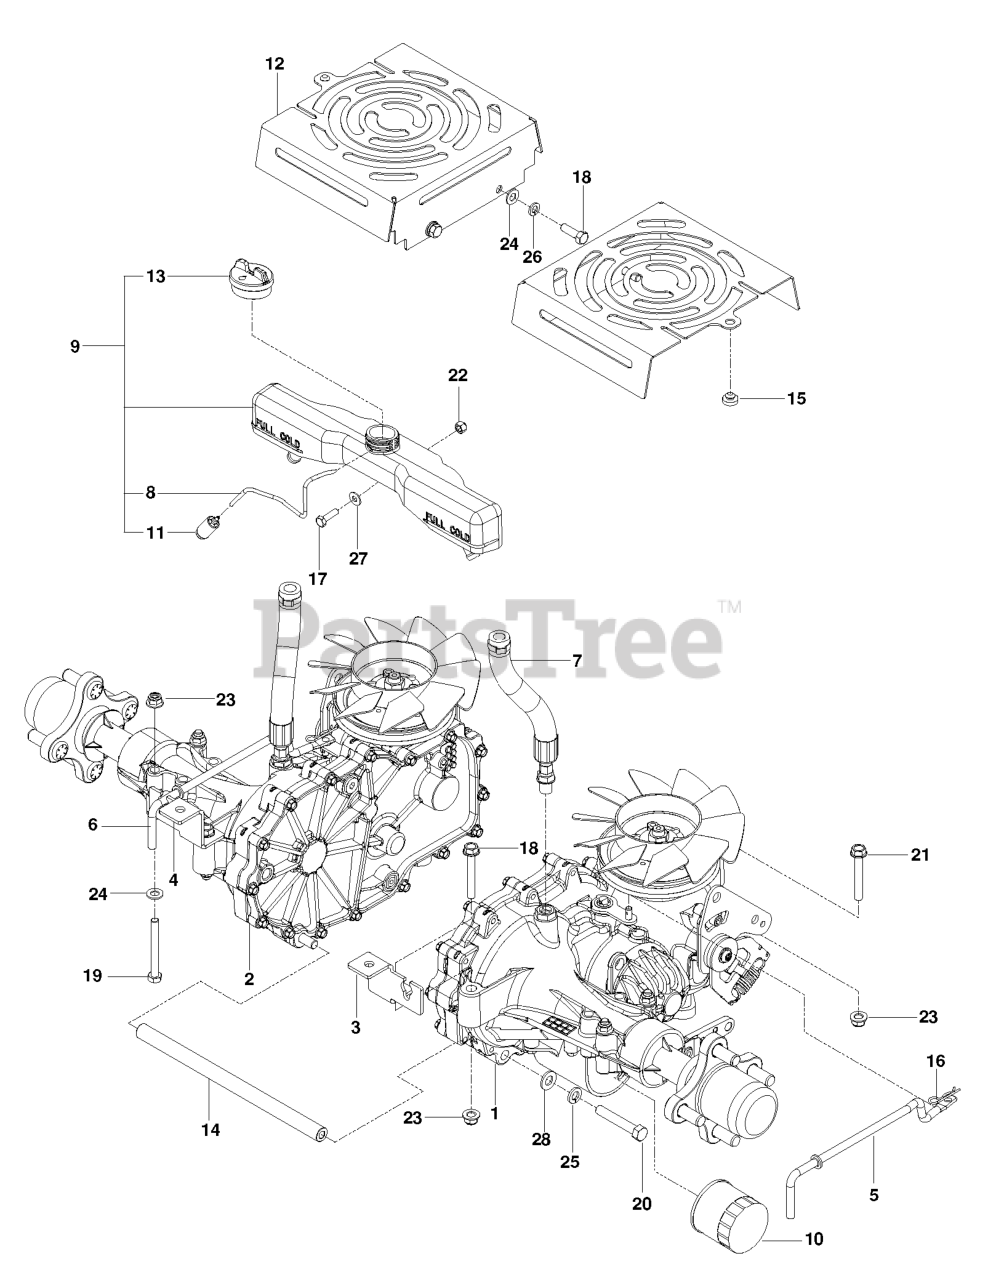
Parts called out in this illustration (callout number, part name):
1	HG_TRANS ZT-3100 LT
2	HG_TRANS ZT-3100 RT
3	BRACKET.TRANS.LT.BLACK
4	BRACKET, TRANS, RT BLACK
5	LINKAGE, LEFT BYPASS
6	LINKAGE, RIGHT BYPASS
7	HOSE ASSY, EXPANSION
9	TANK EXPANSION W/CAP
10	HG_FILTER, ZT4800 52114
11	FUEL PICK-UP ASSY
12	SHIELD FAN BLACK
13	CAP EXPANSION W/SEAL
14	TUBE, SPACER, 3400
15	GROMMET, BUMPER
16	HAIRPIN #2
17	HCS 1/4-20X7/8 GR5
18	HCS 5/16C X 1
19	HCS 5/16C X 2-3/4
20	HCS 3/8-16X2-1/4 LOC PATCH GR8
21	HHFS 5/16-18 X 2.25 GD 5
22	NUT.1/4-20.HEX.NYLOC.ZD
23	5/16-18 NYLOC FLANGE NUT
24	FLAT WASHER 5/16 SAE
25	SLW 3/8 STD
26	WASHER.LOCK.HVY.HLCL.SPR.5/16
27	WASHER 1/4 SAE
28	WASHER 3/8 SAE FLAT
